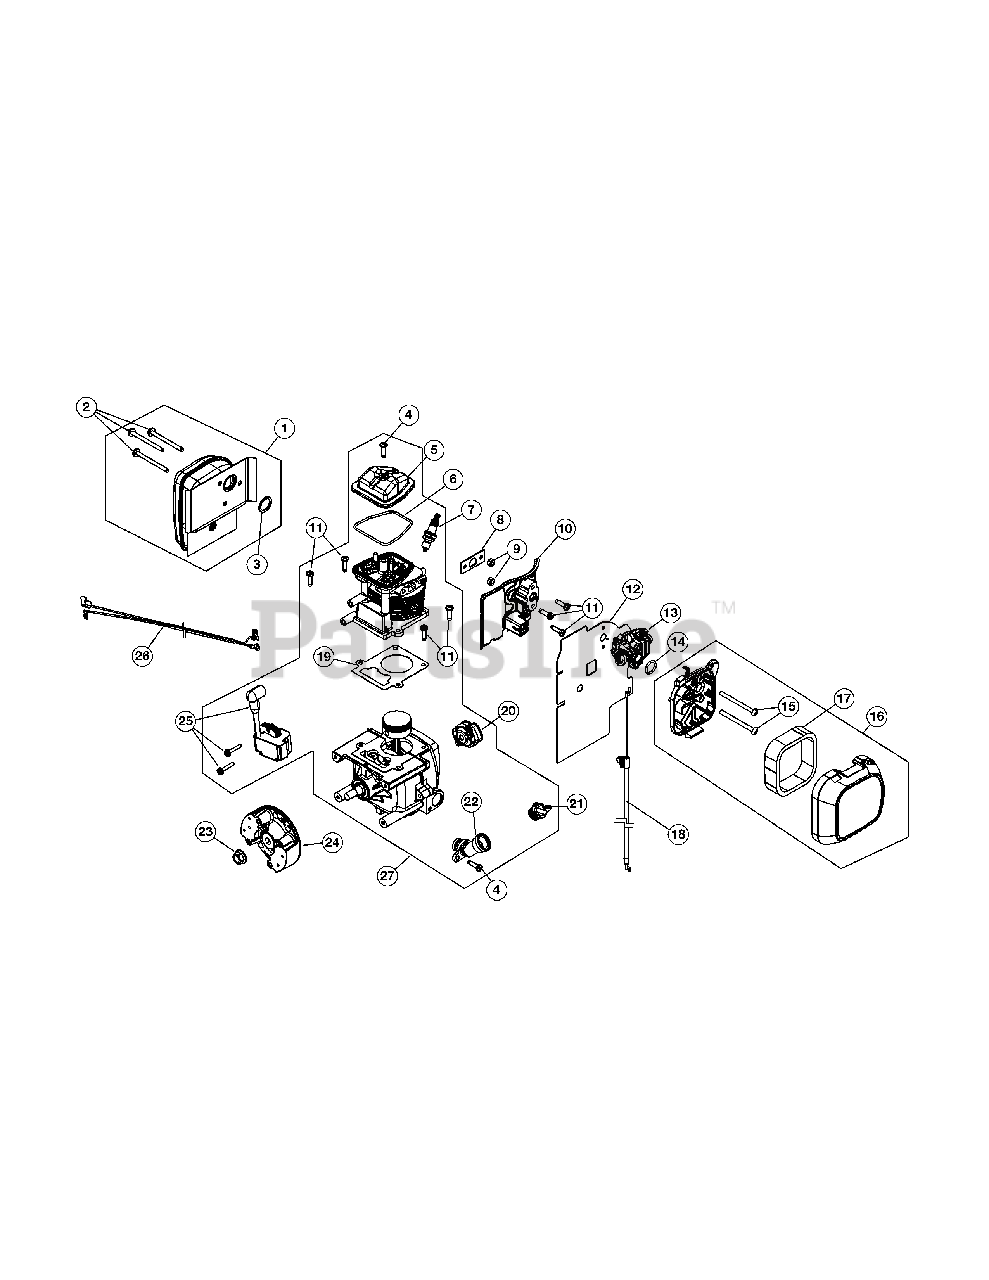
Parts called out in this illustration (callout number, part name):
1	Muffler Assembly (Incl. Ref No. 2 & 3)
2	Muffler Screw
3	Muffler Gasket
5	Rocker Cover
6	Rocker Cover O-Ring
7	Spark Plug
8	Insulator Gasket
10	Insulator
11	Screw
12	Carburetor Gasket
13	Carburetor
14	Carburetor O-Ring
16	Air Cleaner Assembly (Incl. Ref No. 16)
17	Air Filter
18	Throttle Cable
19	Cylinder Gasket
20	Pawl Assembly
21	Oil Plug
22	Oil Fill Tube (Incl. Ref No. 3)
24	Flywheel Asssembly
25	Module Assembly
26	Lead Wire
27	Short Block Assembly
